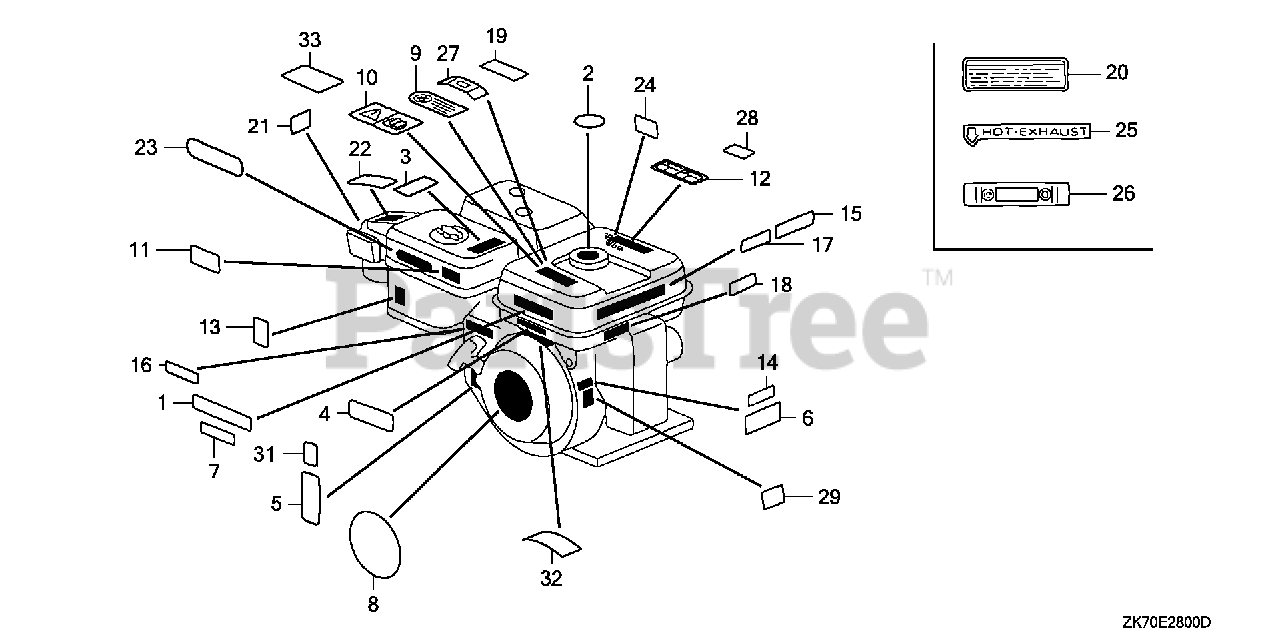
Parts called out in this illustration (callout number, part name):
1	LABEL, CAUTION (ENGLISH, ETC.)
8	EMBLEM (4.0)
13	MARK, CHOKE
17	MARK, OIL ALERT (ENGLISH)
